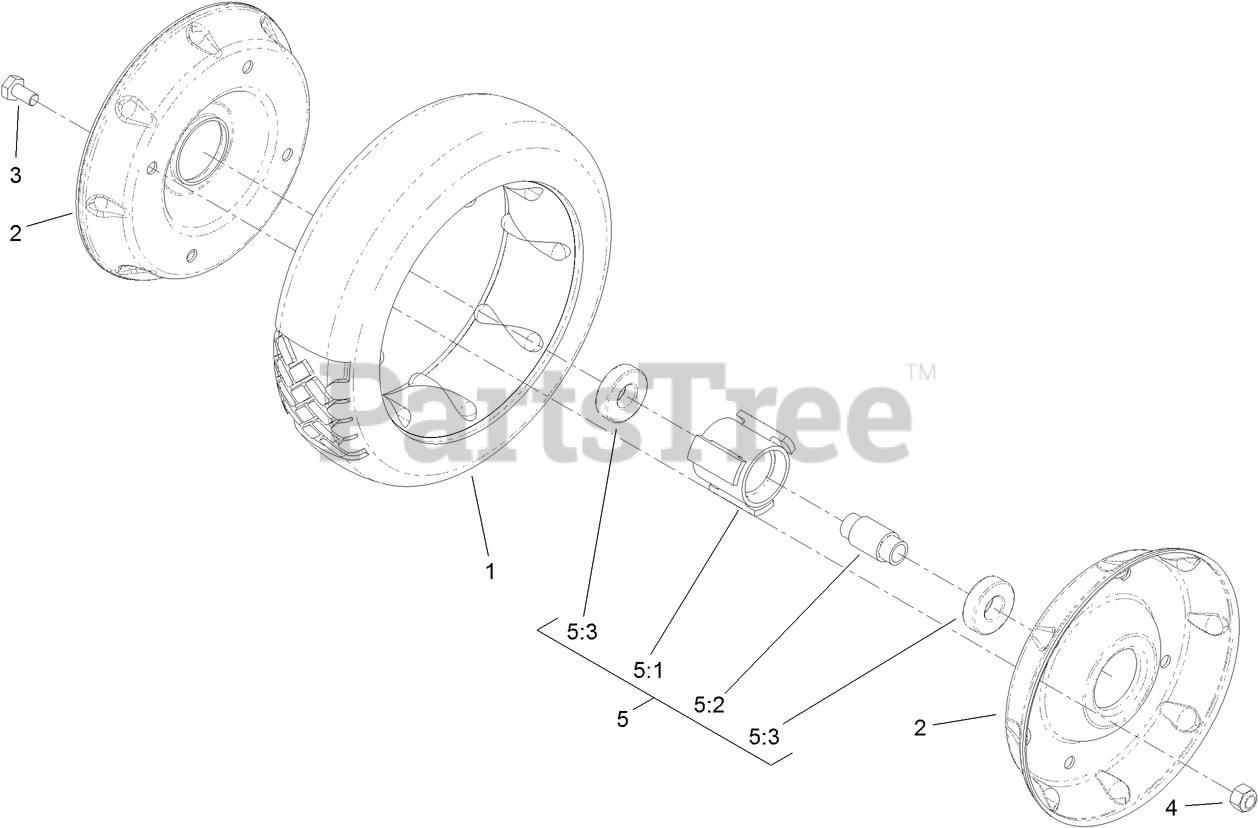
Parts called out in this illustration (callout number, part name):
2	RIM-HALF, WHEEL
3	SCREW-HH
4	NUT-LOCK, NI
5	HUB AND BEARING ASM
5:1	HUB-BEARING
5:2	SPACER-BEARING
5:3	BEARING-BALL
